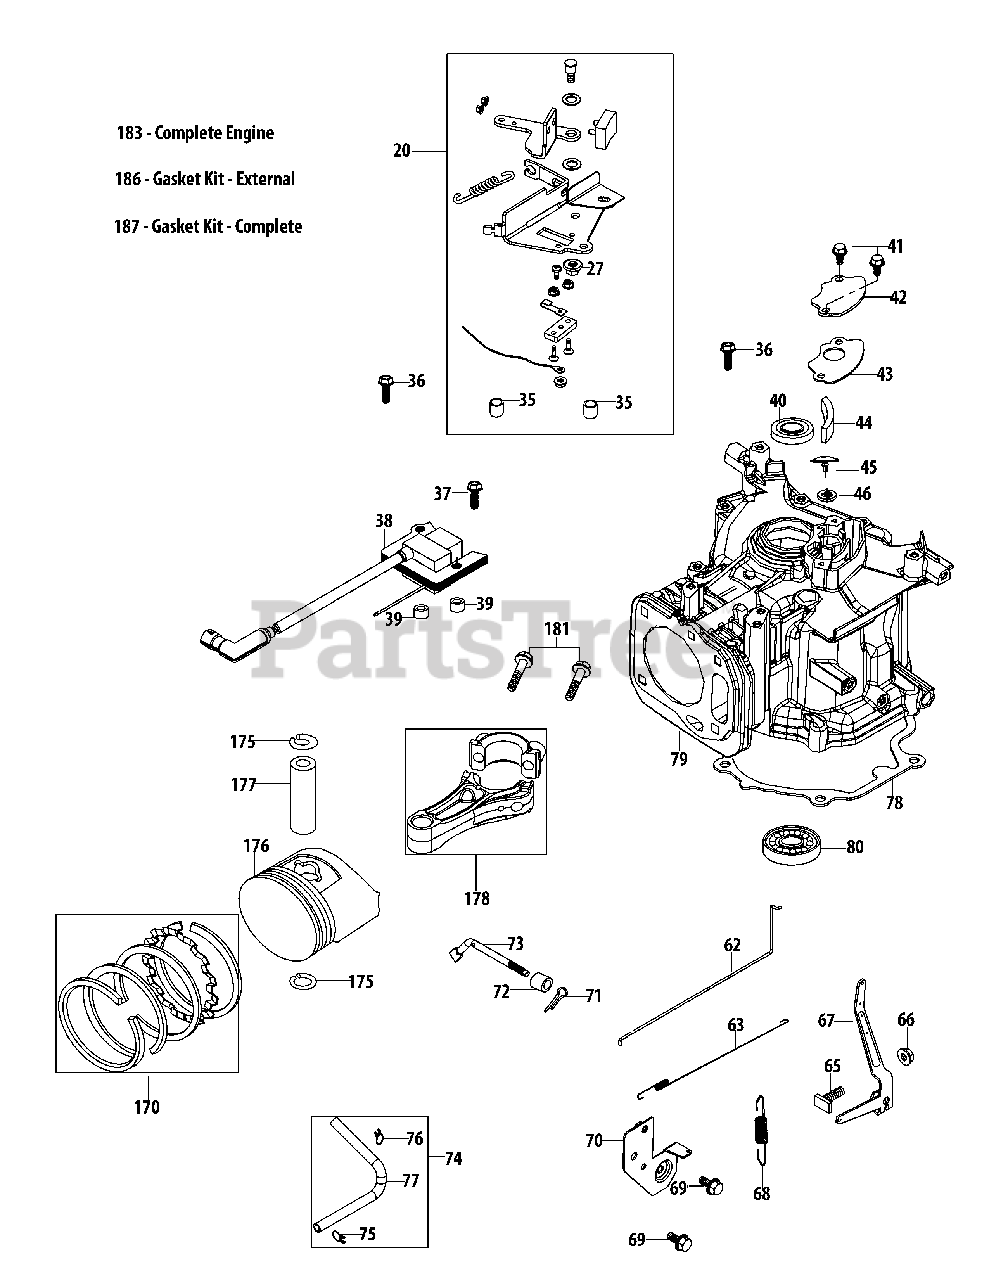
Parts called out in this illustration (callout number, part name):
20	Brake Assembly
27	Brake Arm Nut
35	Brake Spacer
36	Bolt M6X35 Af Base/Brake/Dipstick
37	Bolt M6X30 Af Base/Coil/E-Starter
38	Ignition Coil Assembly
39	Ignition Coil Spacer
40	Upper Crankshaft Seal
41	Bolt M6X14 Multi-Purpose
42	Breather Cover Plate
43	Breather Gasket
44	Breather Screen
45	Breather Valve
46	Breather Valve Base
62	Throttle Linkage
63	Throttle Linkage Spring
65	Governor Arm Bolt
66	Governor Arm Nut M6
67	Governor Arm
68	Governor Spring
69	Bolt M6X12 Component/Vrbl Spd Brkt
70	Component Bracket
71	Governor Arm Shaft Cotter Pin
72	Governor Seal
73	Governor Arm Shaft
74	Breather Hose Assembly
75	Breather Hose Clamp
76	Breather Hose Clamp
77	Breather Hose
78	Crankcase Cover Gasket
79	Short Block Assembly
80	Main Bearing
170	Piston Ring Set
175	Piston Pin Snap Ring
176	Piston
177	Piston Pin
178	Connecting Rod Assembly
181	Connecting Rod Bolt
183	Complete Engine
186	Gasket Kit - External
187	Gasket Kit - Complete
